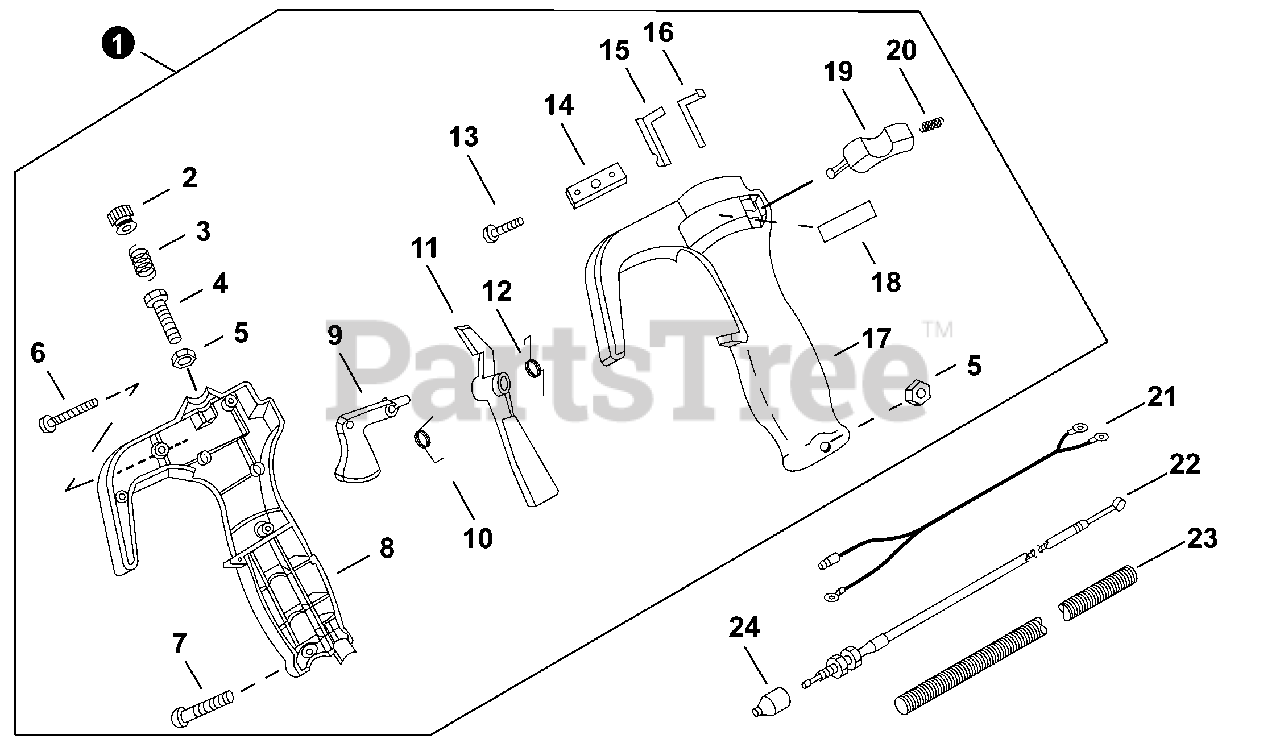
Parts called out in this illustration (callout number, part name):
1	THROTTLE CONTROL ASSY
8	GRIP, RIGHT
9	TRIGGER, THROTTLE
11	LOCKOUT, THROTTLE
17	GRIP, LEFT
18	LABEL, STOP-START
19	SWITCH, START-STOP
22	CABLE, THROTTLE
23	TUBE, FLEXIBLE
24	CAP, DUST
